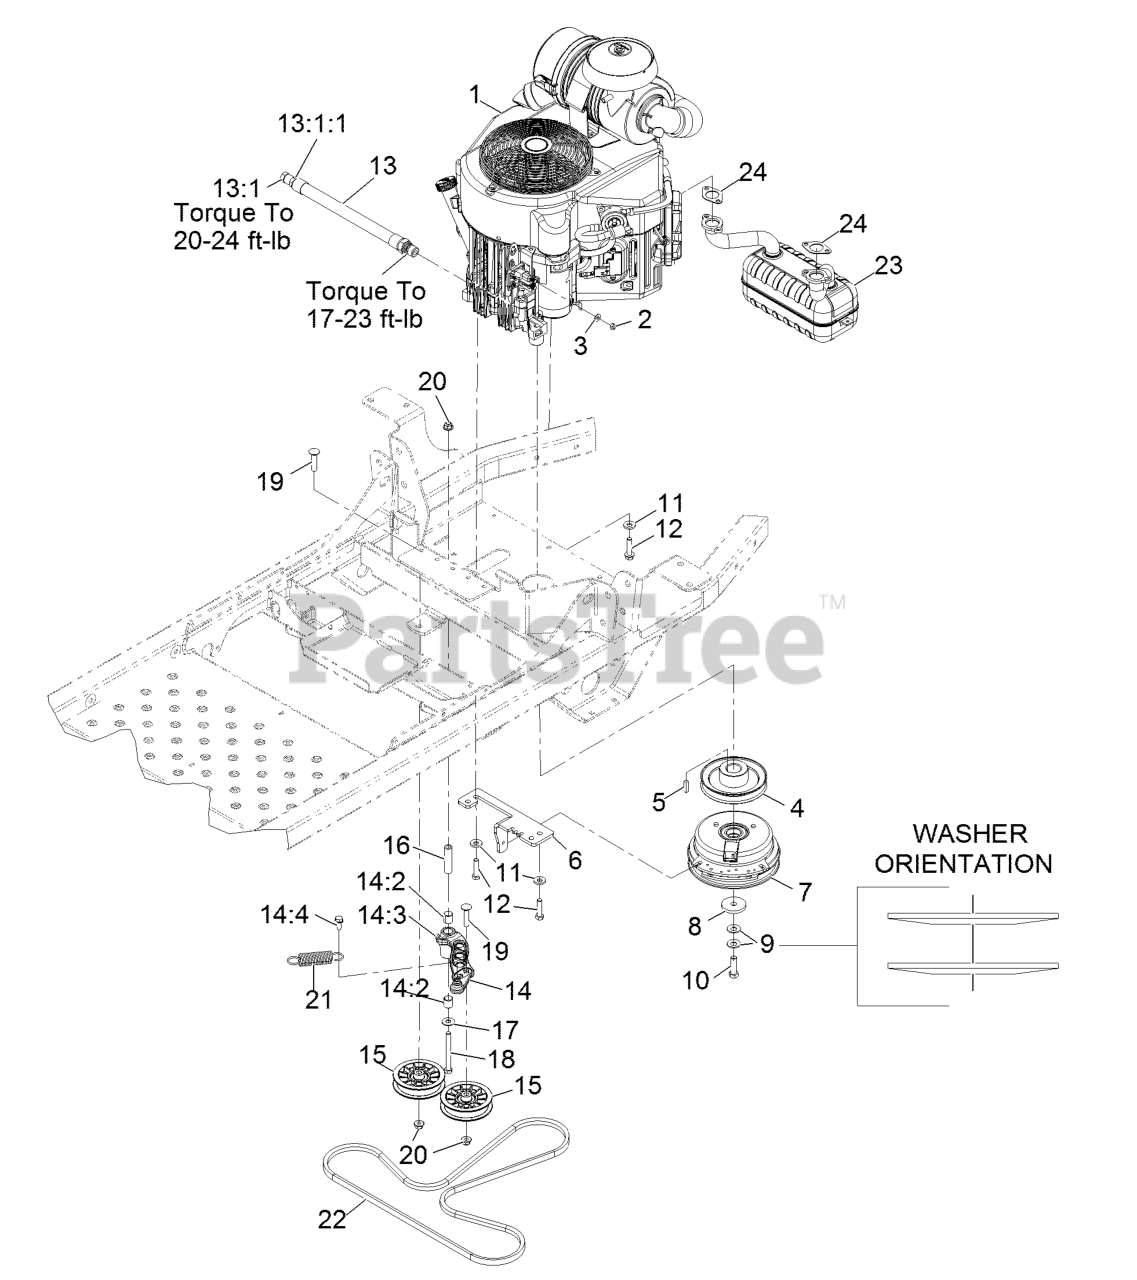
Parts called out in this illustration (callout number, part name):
2	NUT-HEX
3	WASHER-FLAT
4	SHEAVE-PUMP, DRIVE
6	ANCHOR-CLUTCH
8	WASHER-CLUTCH
9	WASHER-SPRING
10	SCREW-HH 7/16-20 X 1 1/2 W/LOCTITE
11	WASHER-BELLEVILLE
12	SCREW-HH
13	ENGINE OIL DRAIN HOSE ASM
13:1	PLUG-HH
13:1:1	O-RING
14	IDLER ARM ASM
14:2	SLEEVE-BEARING
14:3	FITTING-GREASE, 90 DEG
14:4	SCREW-THD ROLL, HWH
15	PULLEY-FLAT IDLER
16	BUSHING-PIVOT, IDLER
17	WASHER-FLAT
18	SCREW-CARR
19	SCREW-CARR
20	NUT-HF, NI
21	SPRING-EXTENSION
22	V-BELT
23	MUFFLER-KAWASAKI
24	GASKET-EXHAUST
